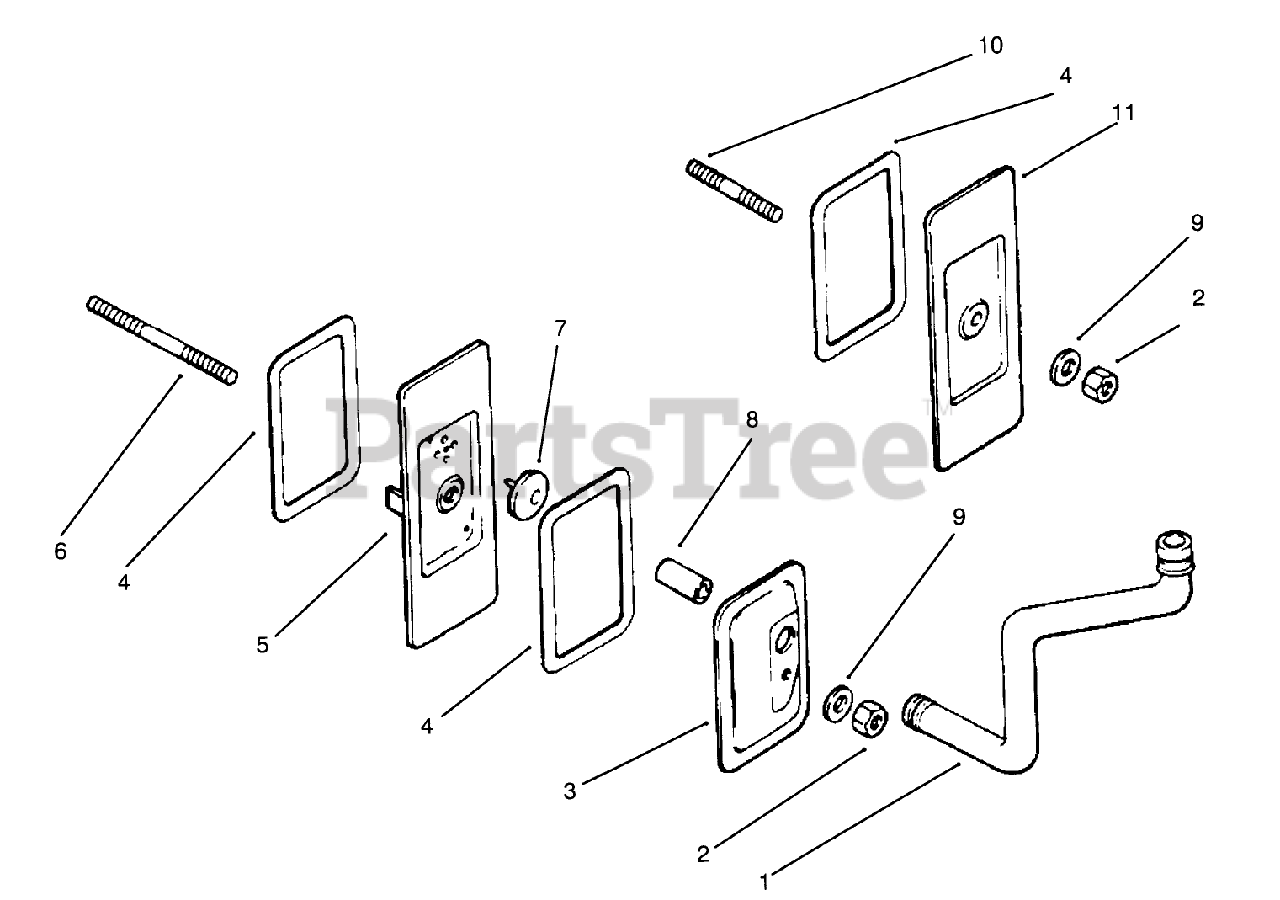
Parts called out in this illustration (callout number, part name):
1	Hose-Breather
3	Cover-#1 Upper Cyl. Valve
4	Gasket-Cover
5	Cover-#1 Lower Cyl. Valve
7	Valve-Breather
8	Seal-Breather
9	Washer
10	Stud-Valve Cover
11	Cover Cylinder Valve
